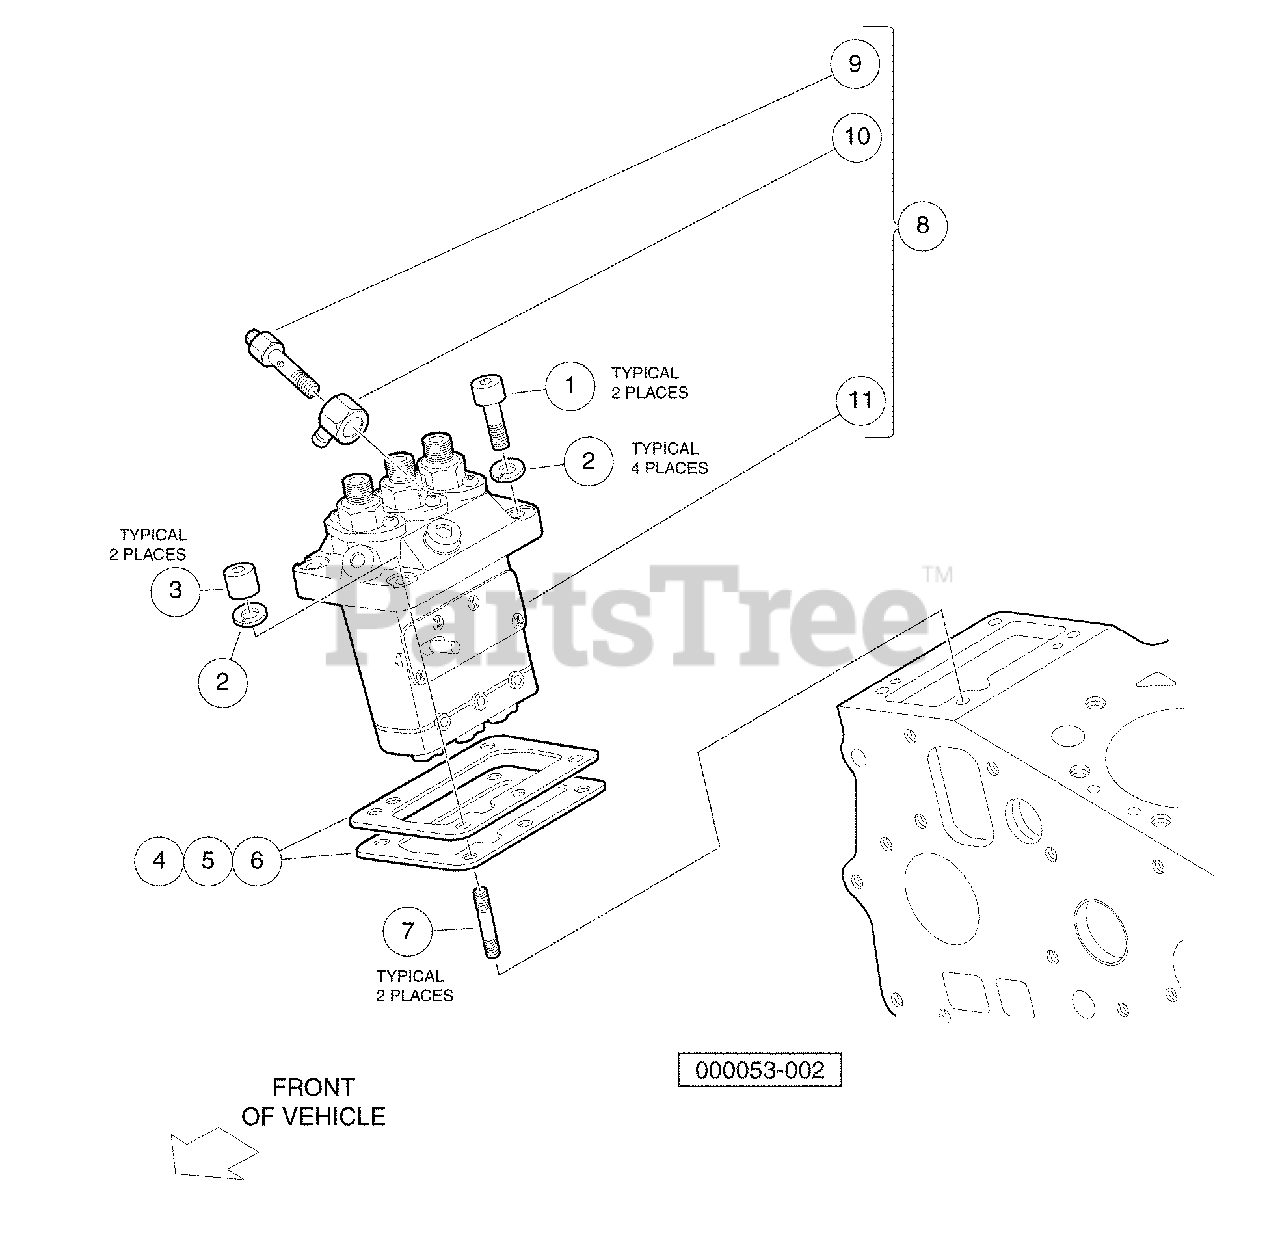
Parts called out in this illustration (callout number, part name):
1	Bolt, Hex-Head, M5 X 0.75 X
2	Washer, Spring, M6, D722
3	Nut, Special
4	Shim, Injection Pump, 0.20 mm.
5	Shim, Injection Pump, 0.25 mm.
6	Shim, Injection Pump, 0.30 mm.
7	Stud, M5 X 25
8	Assembly, Fuel Injection Pump
9	Screw, Hollow, D722, Inj Pump
10	Joint, Eye
11	Pump, Injection
